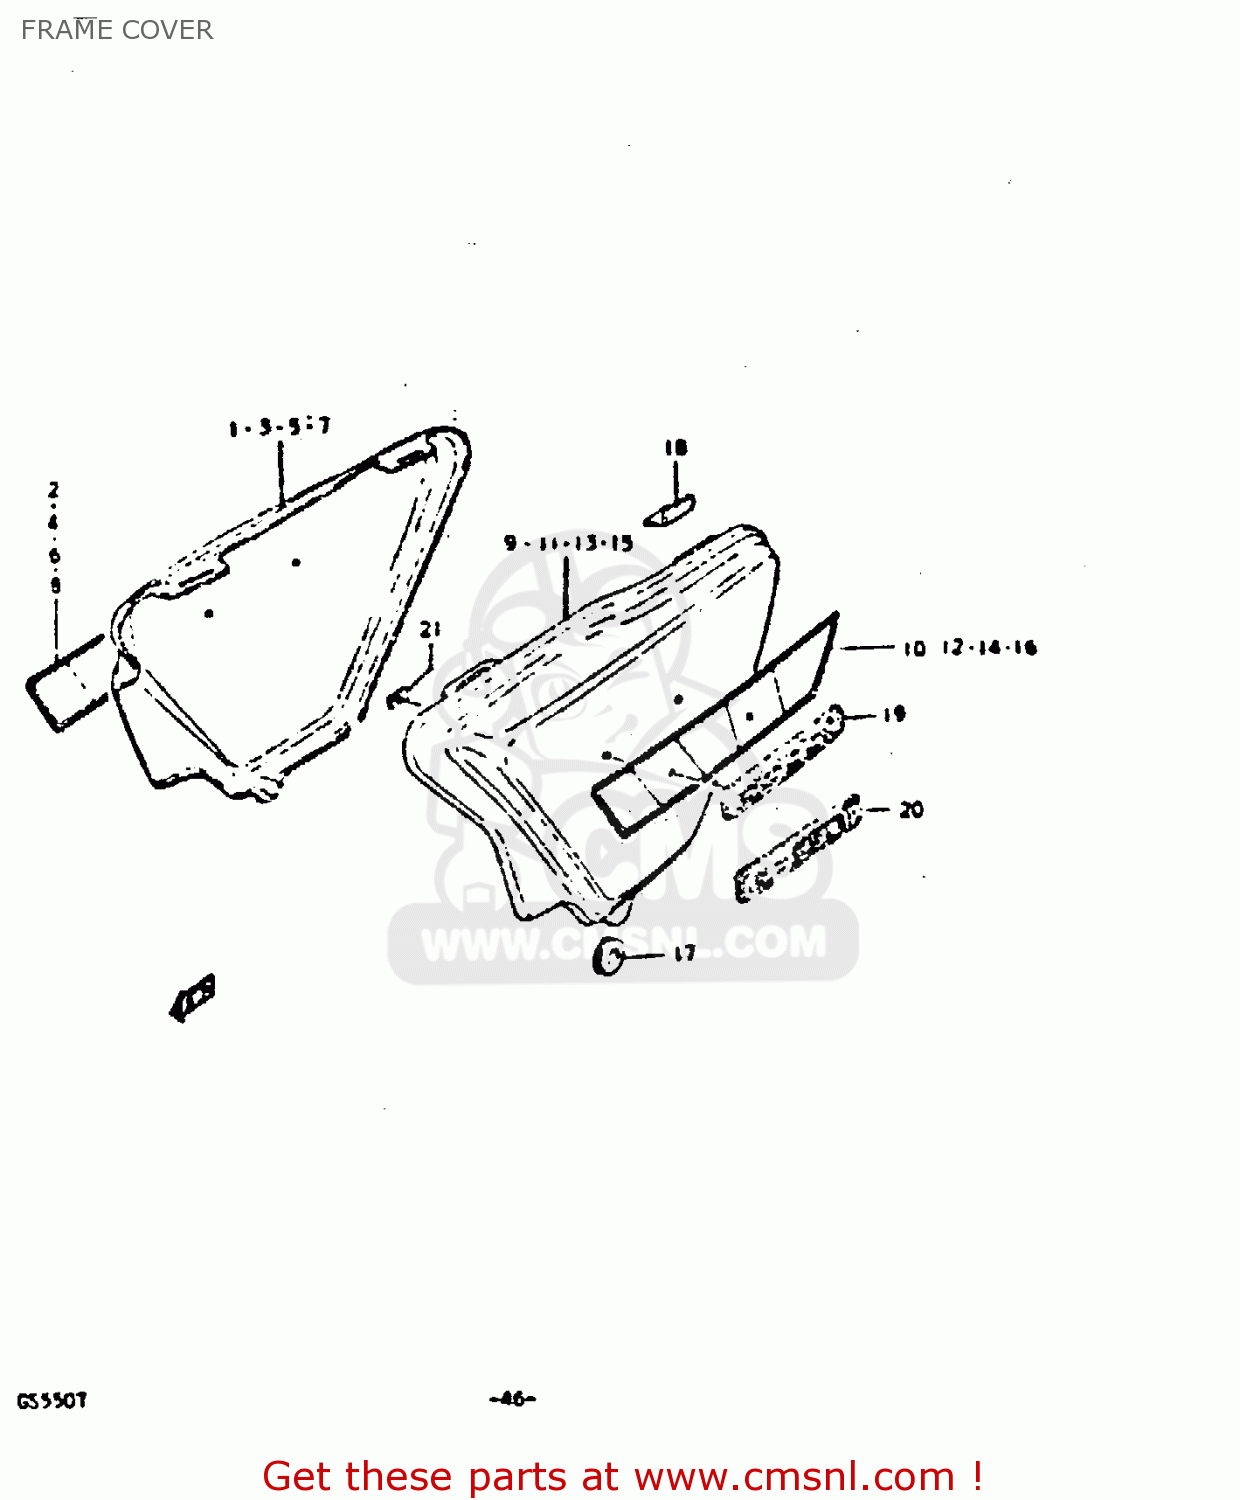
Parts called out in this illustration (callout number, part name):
1	COVER,FRAME,RIGHT
2	TAPE
3	COVER, FRAME RH
4	TAPE
5	COVER,FRAME,RIGHT
6	TAPE
9	COVER,FRAME,LEFT
10	TAPE
11	COVER, FRAME LH
12	TAPE
13	COVER,FRAME,LEFT
14	TAPE
17	CUSHION
18	CUSHION,FRAME COVER
19	EMBLEM,FRAME COVER
20	EMBLEM,FRAME COVER
21	NUT
